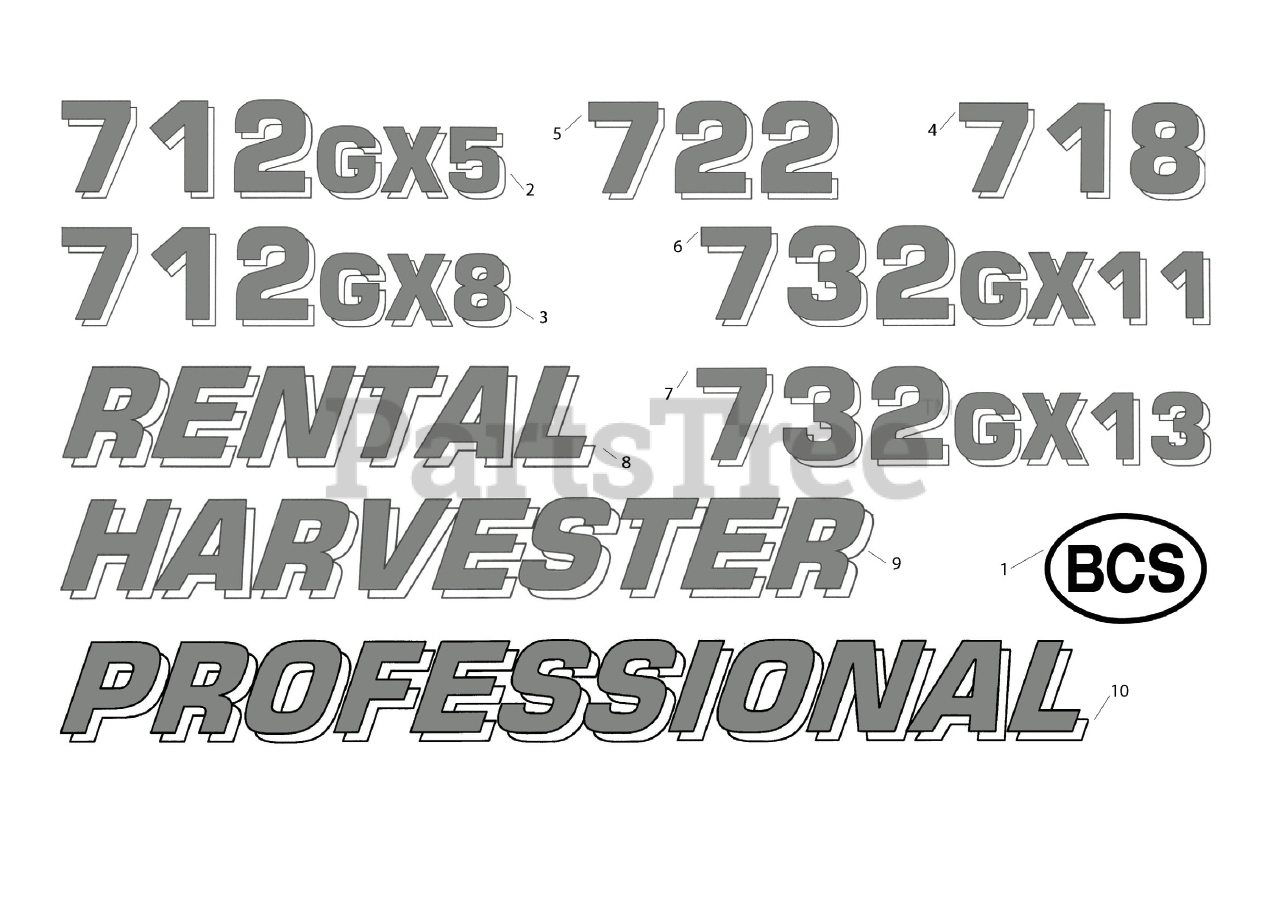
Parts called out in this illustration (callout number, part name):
1	DECAL, BCS LOGO
2	DECAL, 712GX5
3	DECAL, 712GX8
4	DECAL, 718
5	DECAL, 722
6	DECAL, 732GX11
7	DECAL, 732GX13
8	DECAL, RENTAL
9	DECAL, HARVESTER
10	DECAL, PROFESSIONAL
